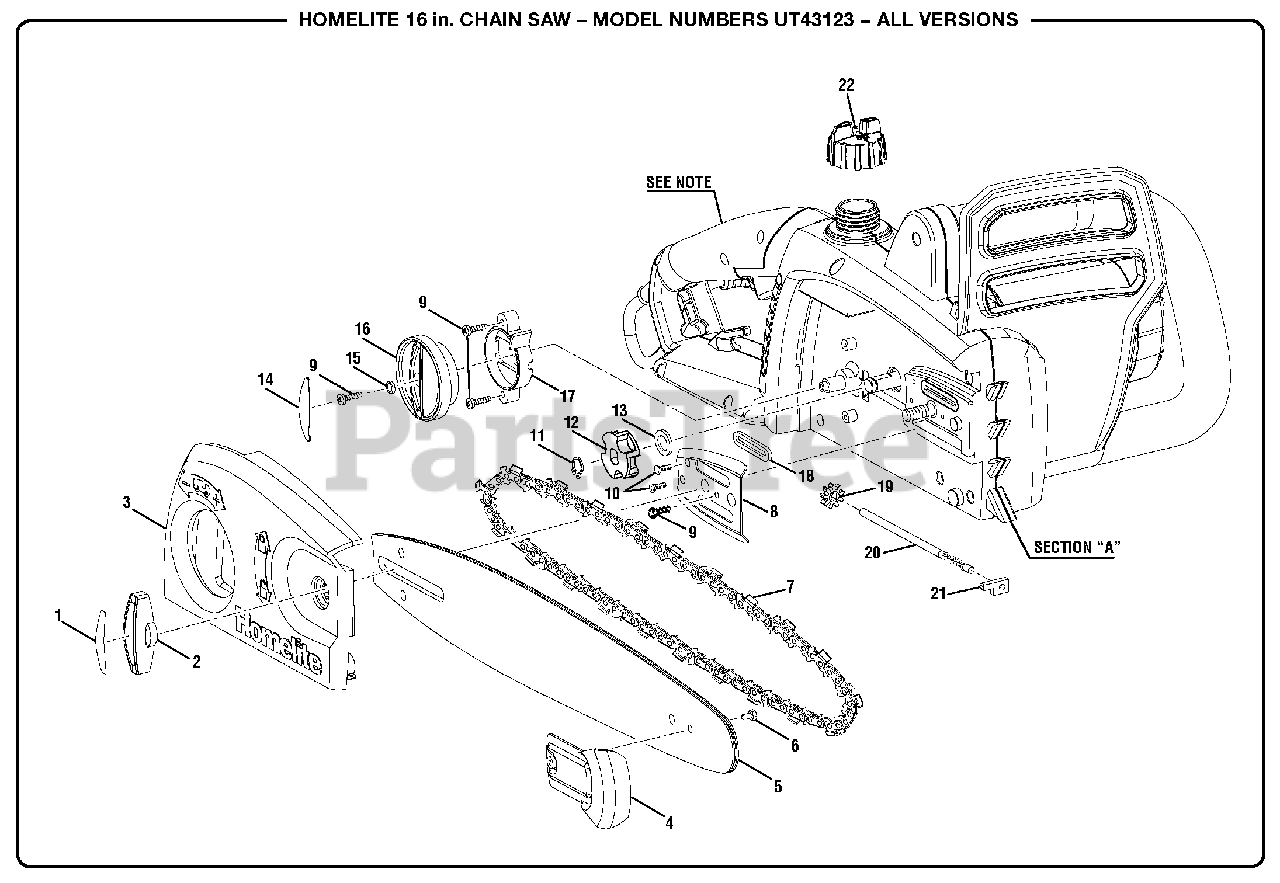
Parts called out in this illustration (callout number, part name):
1	Knob Cover (Chain Cover)
2	Chain Cover Lock Knob
3	Chain Cover
4	SAFE-T-TIP
5	Guide Bar
6	Screw w/Washer
7	Chain (0.375 x 56 Link, 16 in.)
8	Chain Tensioning Adjustment Cover
9	Screw (M4 x 16 mm)
10	Screw (M4 x 12 mm, Countersunk)
11	Retaining Ring
13	Felt Washer
14	Knob Cover (Chain Tensioning)
15	Washer (M4)
16	Chain Tensioning Knob
17	Knob Bracket
18	Seal Ring
19	Adjustment Gear
20	Adjustment Stem
21	Adjustment Pin
22	Oil Reservoir Cap
